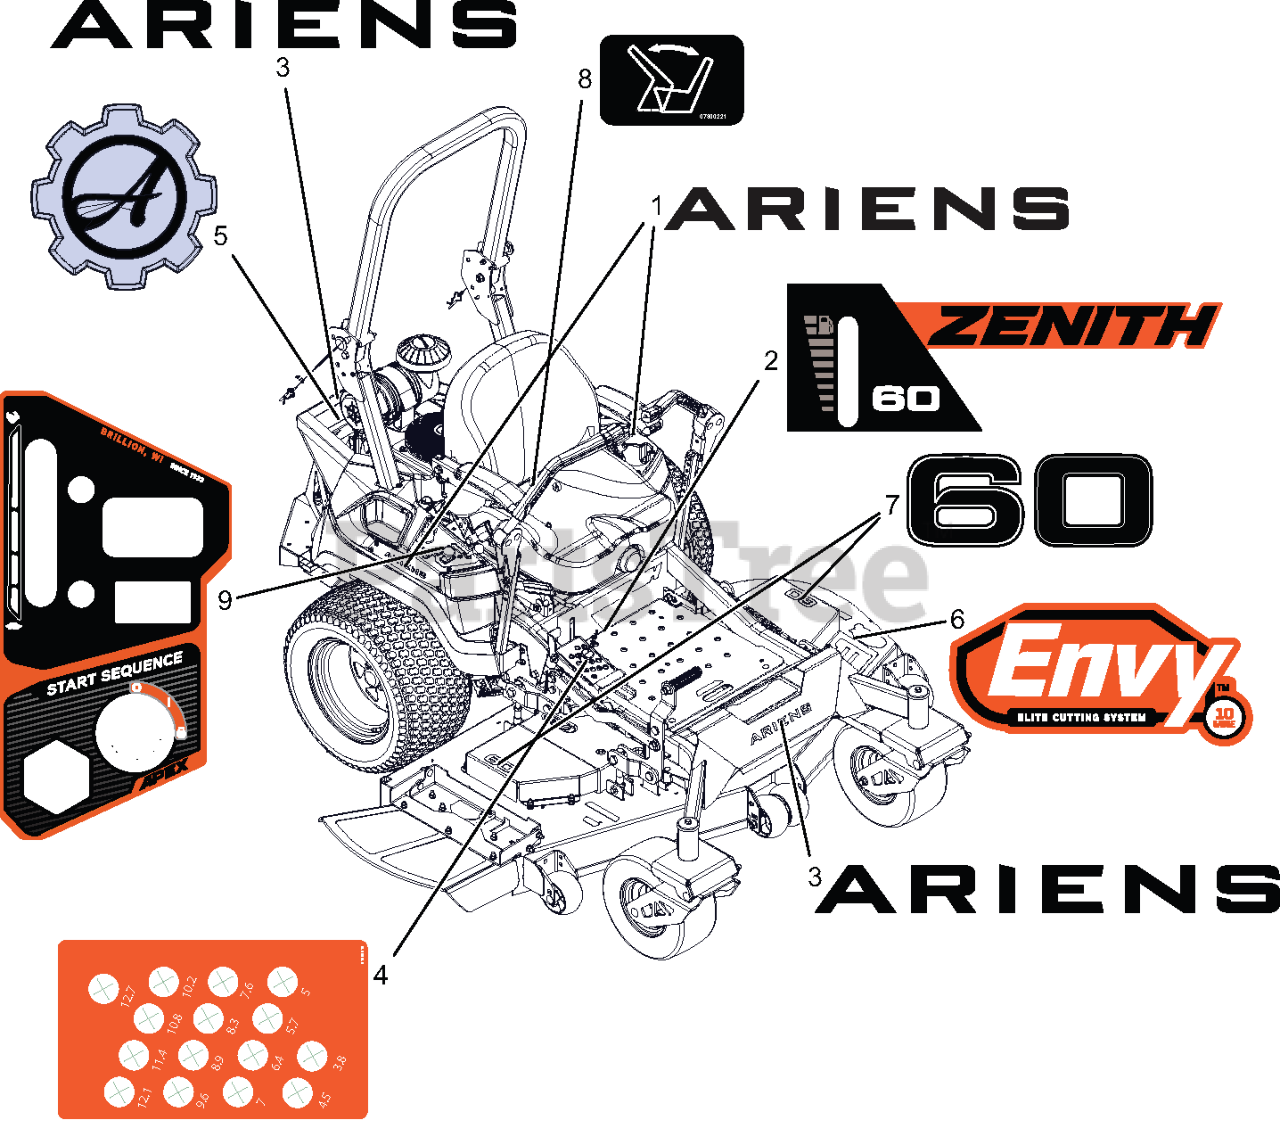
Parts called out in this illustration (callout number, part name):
1	DECAL- ARIENS 6.000" BLACK
2	DECAL- ZENITH 60 KICKPLATE
3	DECAL- ARIENS 9.625" BLACK
4	DECAL, APEX HOC METRIC
5	DECAL- ARIENS GEAR BADGE
6	DECAL- DECK -ENVY
7	DECAL- DECK 60
8	DECAL - SEAT RELEASE
9	DECAL- DASH -APEX & ZENITH
